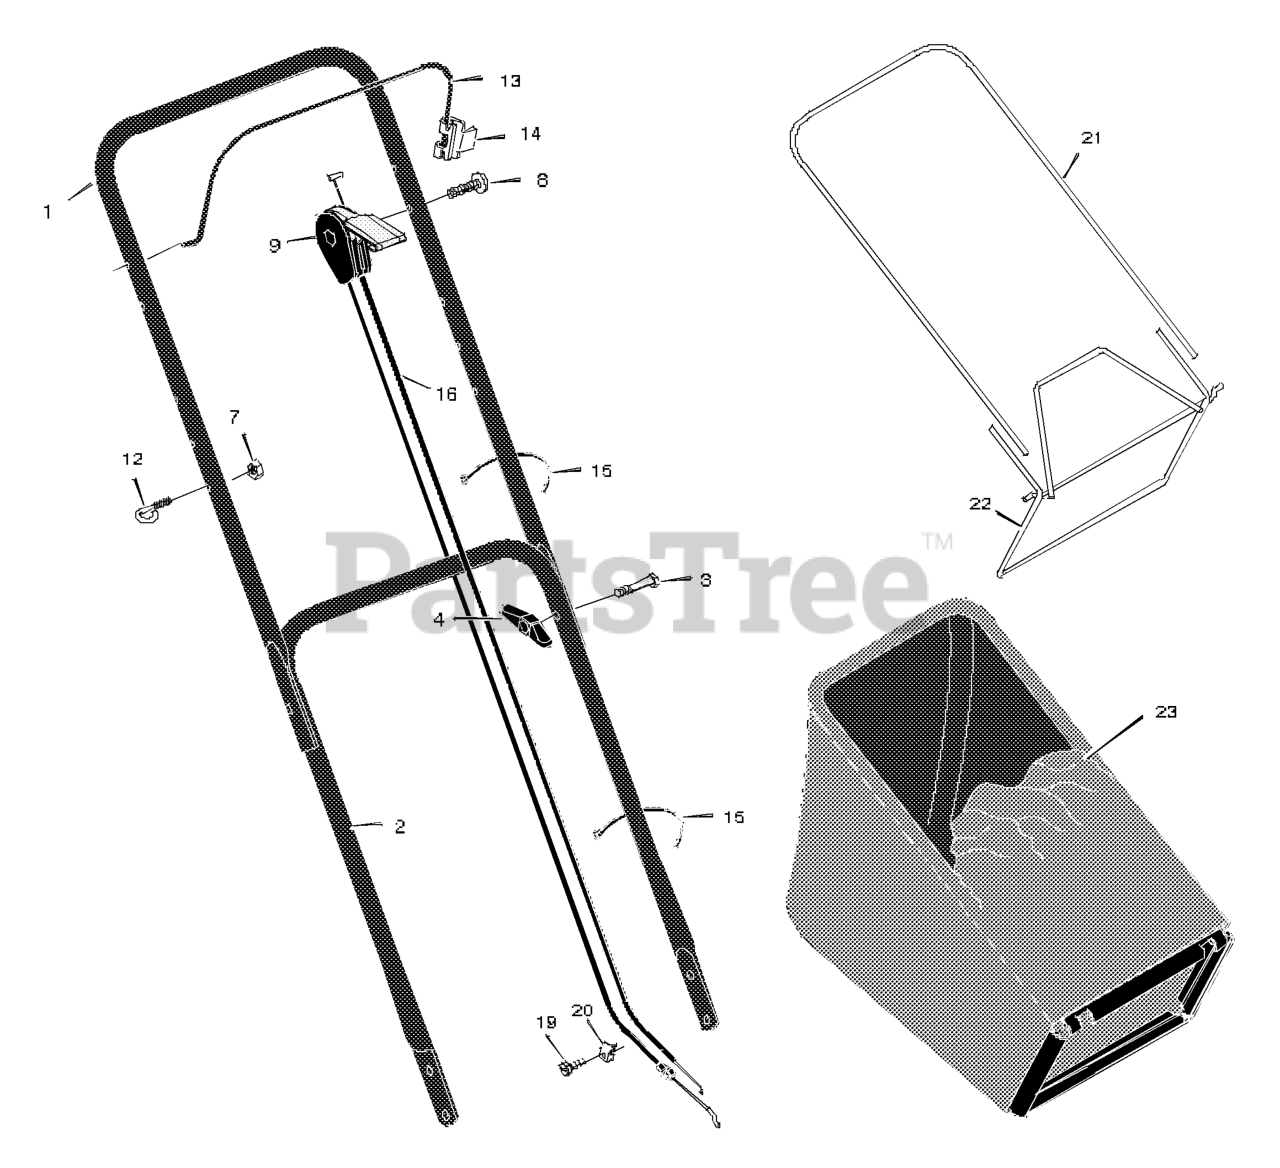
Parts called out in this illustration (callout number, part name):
1	Handle, Upper
2	Handle, Lower
4	Knob, Plastic
7	Locknut
9	Throttle Control
12	GUIDE, ROPE
13	Engine Stop Lever
14	Bracket, Stop Lever
15	Fastener, Cable
16	Engine Stop Cable
21	Frame, Top
22	Frame Assembly
23	Bag, Cloth
